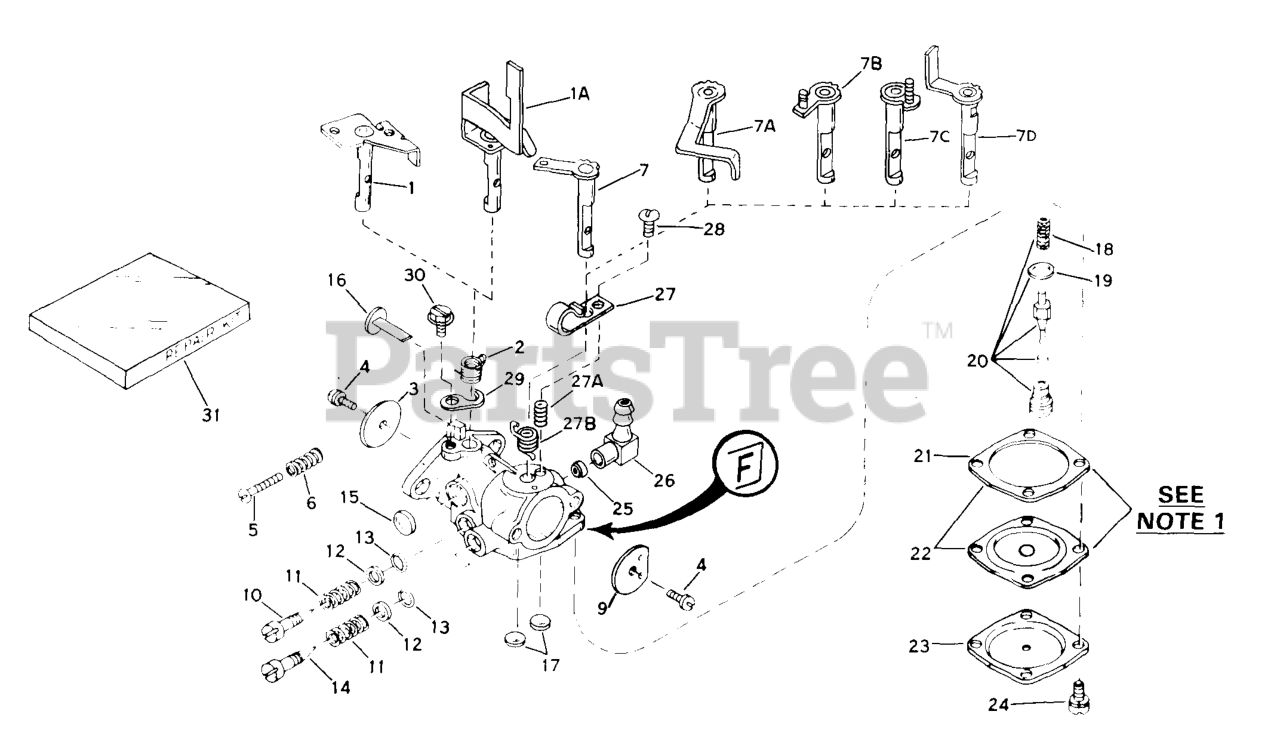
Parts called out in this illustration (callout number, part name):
1	Shaft & Lever Assy, Throttle
2	Spring, Throttle return
3	Shutter, Throttle
4	Screw, Shutter
5	Screw, Idle regulating
6	Spring, Idle speed screw
7	Shaft & Lever Assy., Choke
9	Shutter, Choke
10	Screw, Idle adj
11	Spring, Adj. screw
12	Washer, Adj. screw
13	O-Ring, Adj. screw
14	Screw, Main adj
15	Plug, Welch
17	Plug, Welch
18	Spring, Valve
19	Gasket, Valve seat
20	Inlet Needle, Seat, Gasket & Spring A ssy.
21	Gasket, Diaphragm
22	Diaphragm Assy, (Incl. No. 21)
23	Cover, Diaphragm
24	Screw, Cover
26	Fitting, Fuel line
27A	Spring, Choke stop
31	Repair Kit
